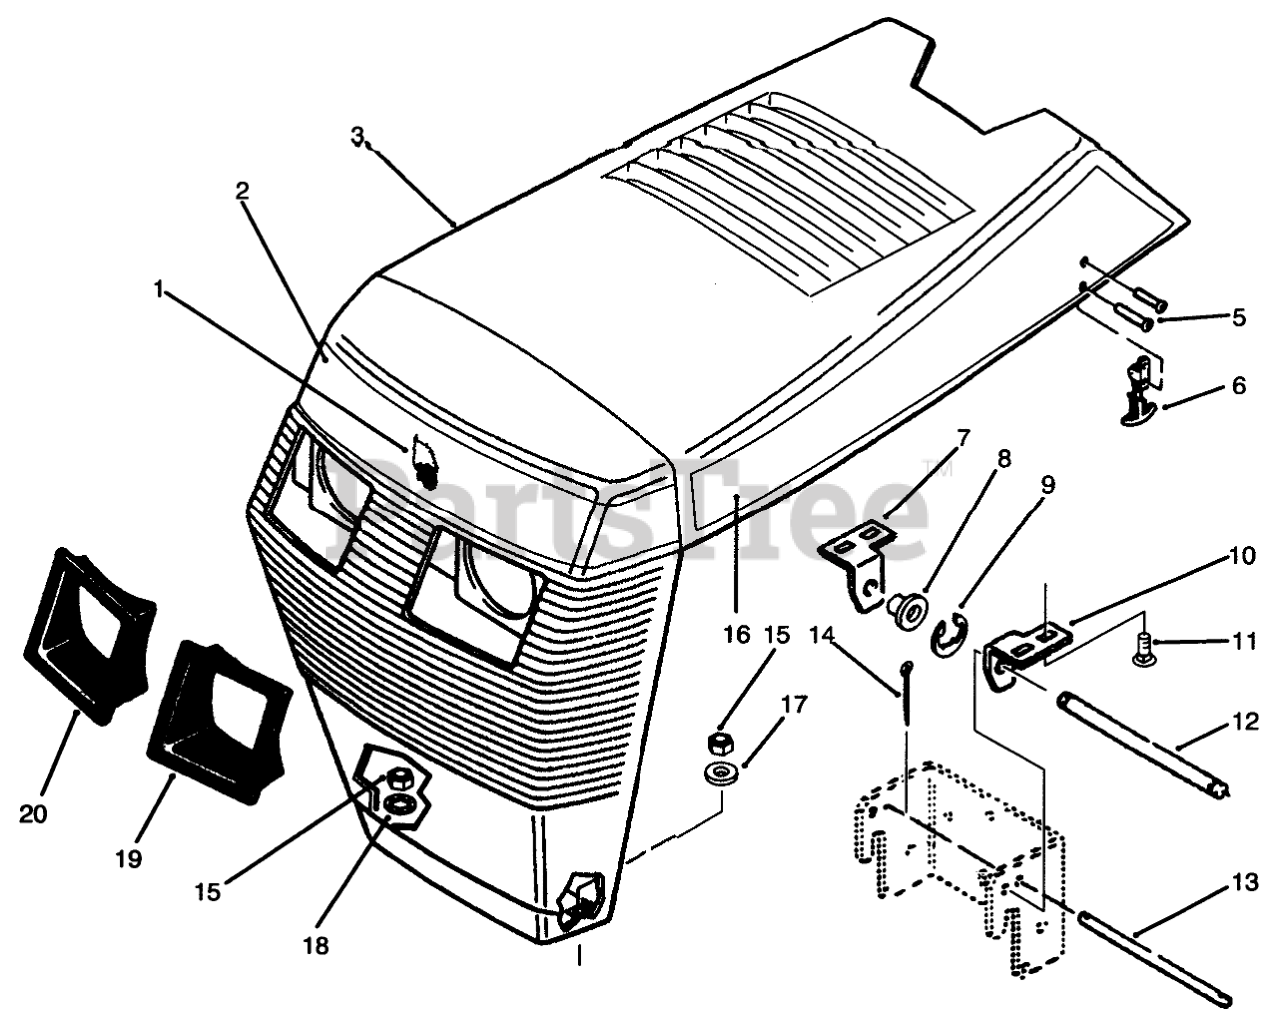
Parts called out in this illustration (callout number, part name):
1	PLATE - LOGO WHL HORSE
2	DECAL-FRONT HOOD, TOP
3	Hood
5	RIVET-POP
6	HANDLE ASM
7	BRACKET-GRILL, R H
8	BUSHING-NYLINER
9	RING-RETAINING
10	BRACKET-GRILL, LH
11	SCREW-CARR
12	ROD-GRILL PIVOT
13	ROD-HOOD STOP
14	PIN-COTTER
15	NUT-LOCK, NI
16	DECAL - LH HOOD TOP
17	WASHER-FLAT
18	WASHER-LOCK, INTERNAL
19	BEZEL-HEADLIGHT, LH
20	BEZEL-HEADLIGHT, RH
